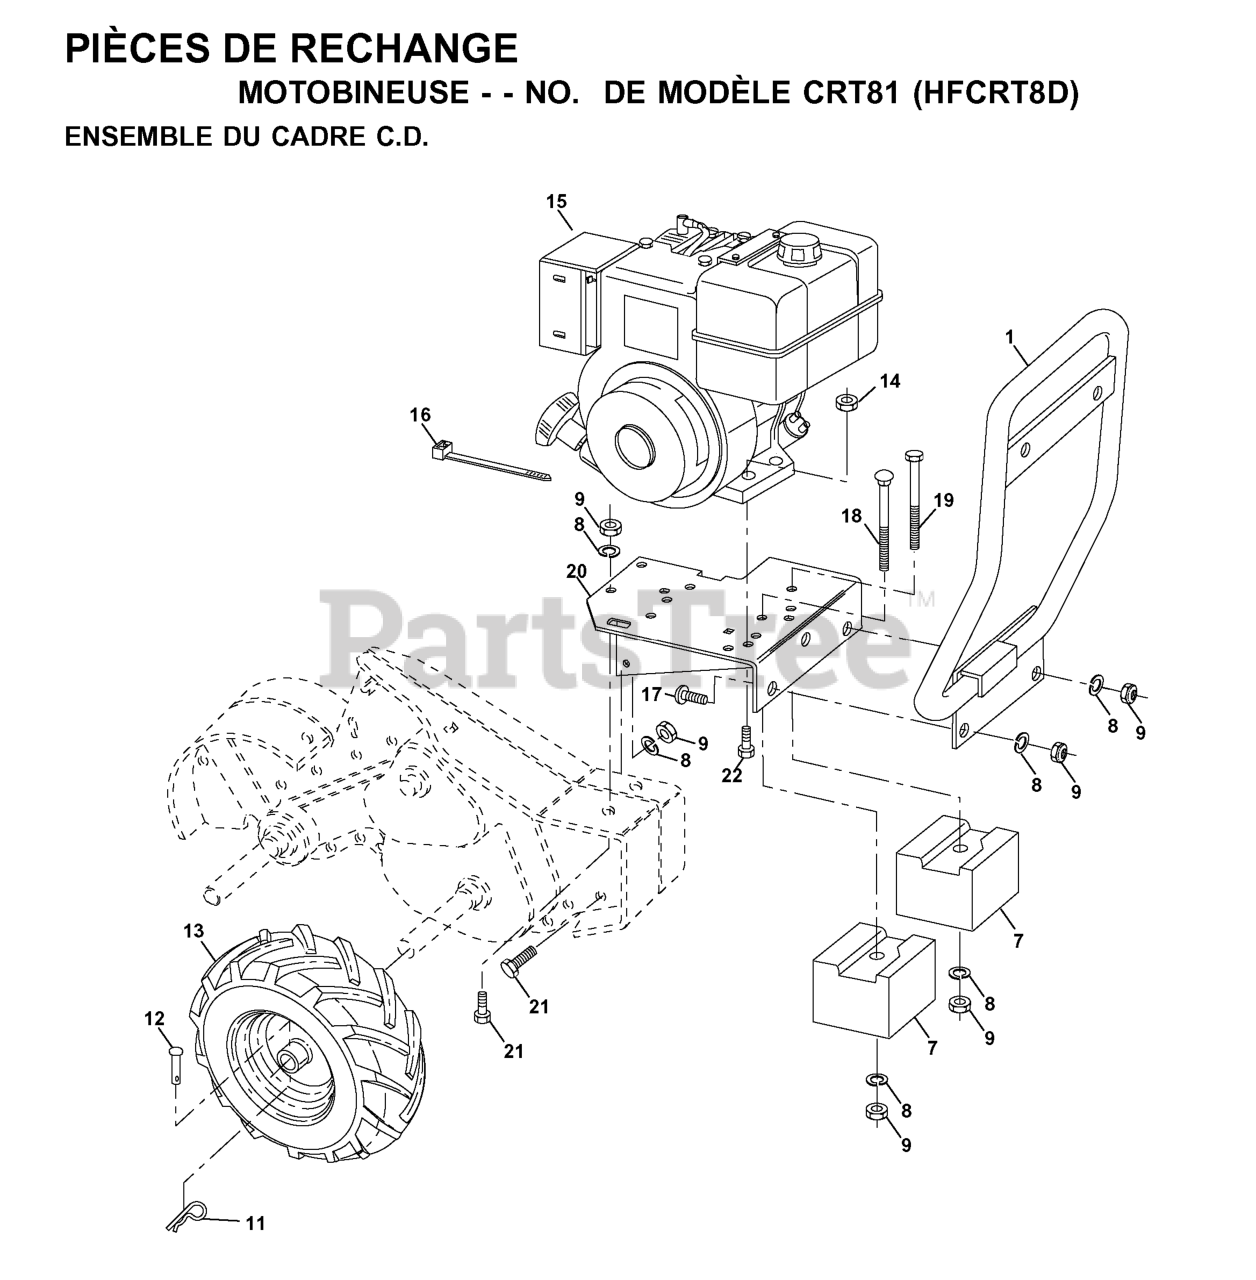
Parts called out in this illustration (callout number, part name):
7	COUNTER WEIGHT RH
8	WASHER, LOCK 3/8
9	NUT.HEX.3/8-16UNC
11	SPRING TI
13	TIRE.16X4-8.CHEVRON.TILLER
14	NUT
16	TIE CABLE CRT
17	BOLT D
18	Bolt, Carriage 3/8-16 x 4-1/2
19	BOLT, HEX 3/8-16X4-1/2
20	ENGINE BRACKET
21	BOLT
22	BOLT, HEX 5/16-18X1-3/4
532124366	RIM
532124718	VALVE STEM LT
